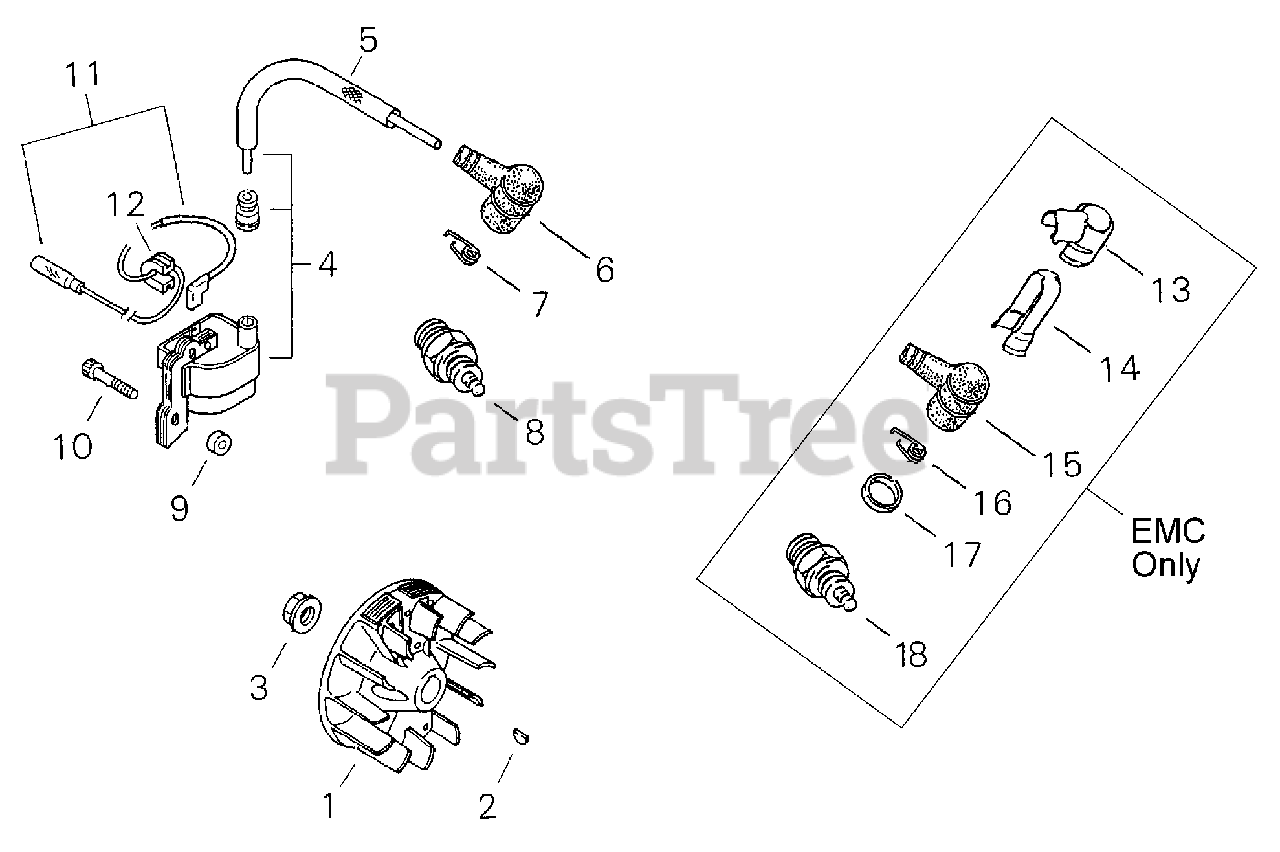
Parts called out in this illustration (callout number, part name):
2	KEY, WOODRUFF 3×10
3	NUT M8
4	COIL ASSY, IGNITION
5	TUBE, INSULATOR
5-1	FLYWHEEL
6	CAP, SPARK PLUG
7	TERMINAL, SPARK PLUG
8	SPARK PLUG - CJ8
9	INSULATOR 4.2×11×6
10	BOLT M4×26
11	LEAD - IGNITION
12	GROMMET, LEAD
13	COVER, CAP
14	SHIELD
15	CAP, SPARK PLUG
16	TERMINAL, SPARK PLUG
17	SEAL, SPARK PLUG
18	SPARK PLUG - BMR6A
